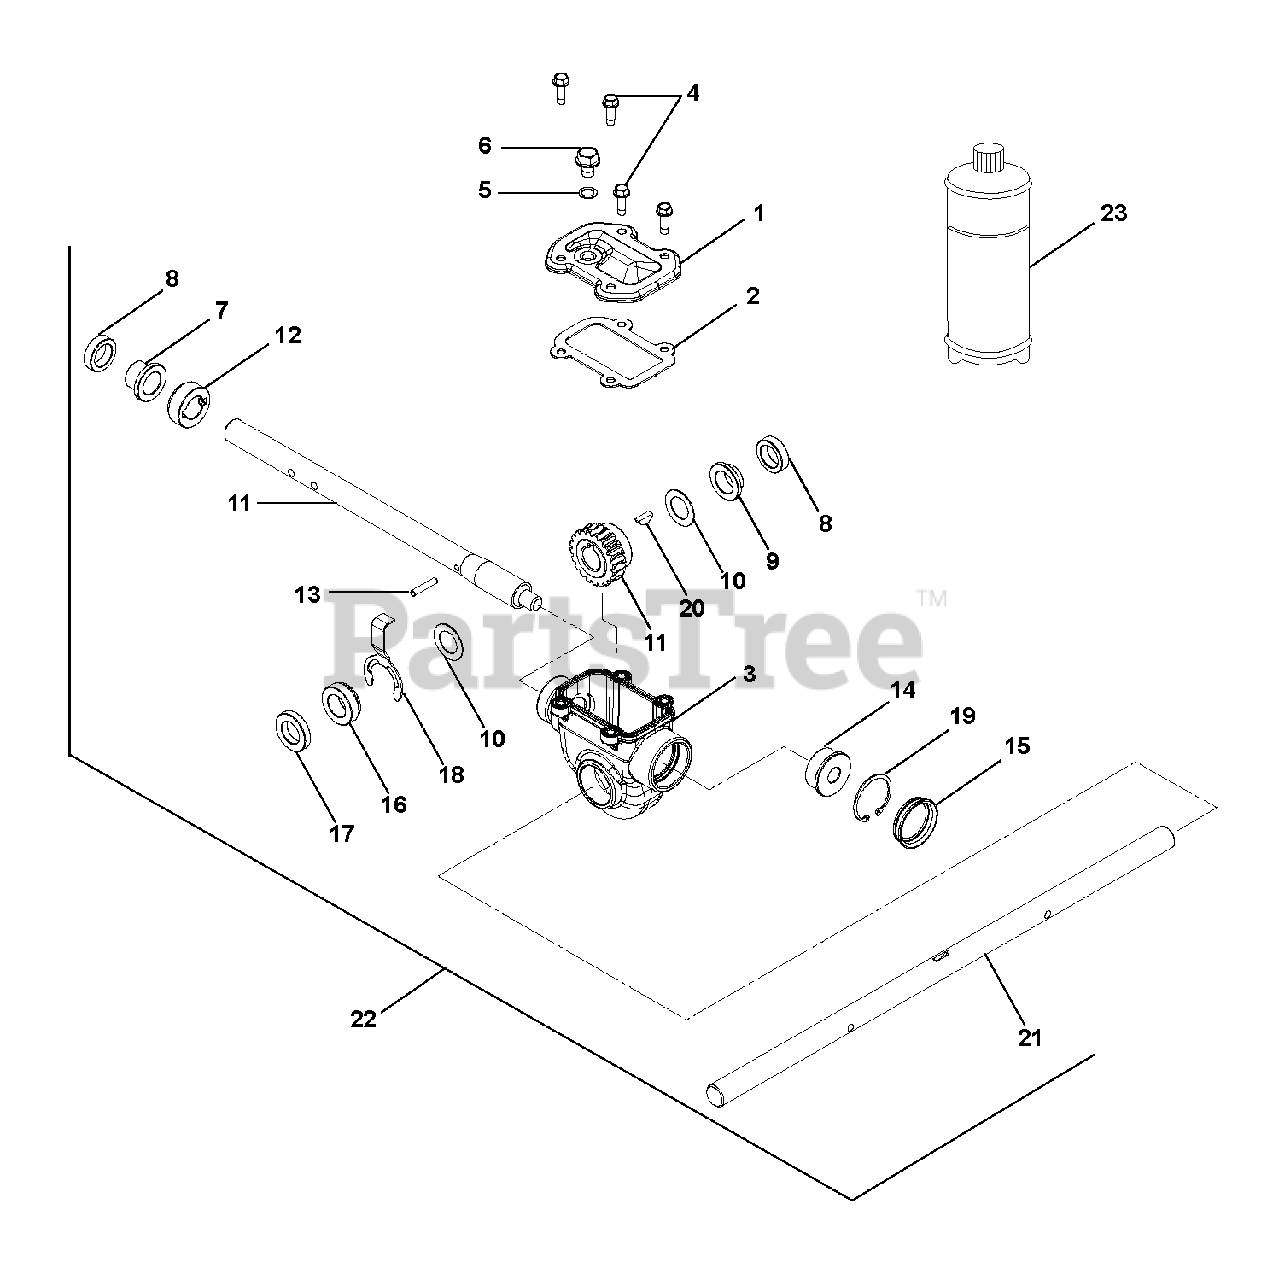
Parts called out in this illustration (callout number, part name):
1	COVER, TOP - COMPACT
2	GASKET, TOP - COMPACT GEARCASE
3	GEARCASE, COMPACT ALUMINUM
4	SCR-TAP .25-20X.75 HWH TR YWZ
5	WSHR-BND-SEAL .38X.75X.11 GALV
6	@SCR-ROLOK .38-16X.50 HWH YWZC
7	BSHG-FLG .755X.878X.75X1.25
8	SEAL-OIL .748X1.125X.312 TBC29
9	BSHG-FLG .755X.878X.424X1.25
10	WSHR-FL-STL .760X1.225X.032 YZ
11	SHAFT AND WORM GEAR ASSEMBLY
12	THRUST COLLAR, .75" ID SLIPFIT
13	PIN-STR .188X1.00 6150
14	BSHG-FLG .503X1.303X.62X1.465
15	COVER, GEAR CASE 1.50"
16	BSHG-FLG COMPACT, RIGHT
17	SEAL-OIL .748X1.300X.250 TBC29
18	BUSHING RETAINER, COMPACT
19	RG-RTNG-INT 1.500X.050
20	KEY-WDRF .19X.63 HRD #61
21	SHAFT, RAKE - 20" (.750 DIA)
22	GEAR CASE, 20" ALUM SM TOP-LD
23	ARIENS L3 LUBE, 8 OZ BOTTLE
